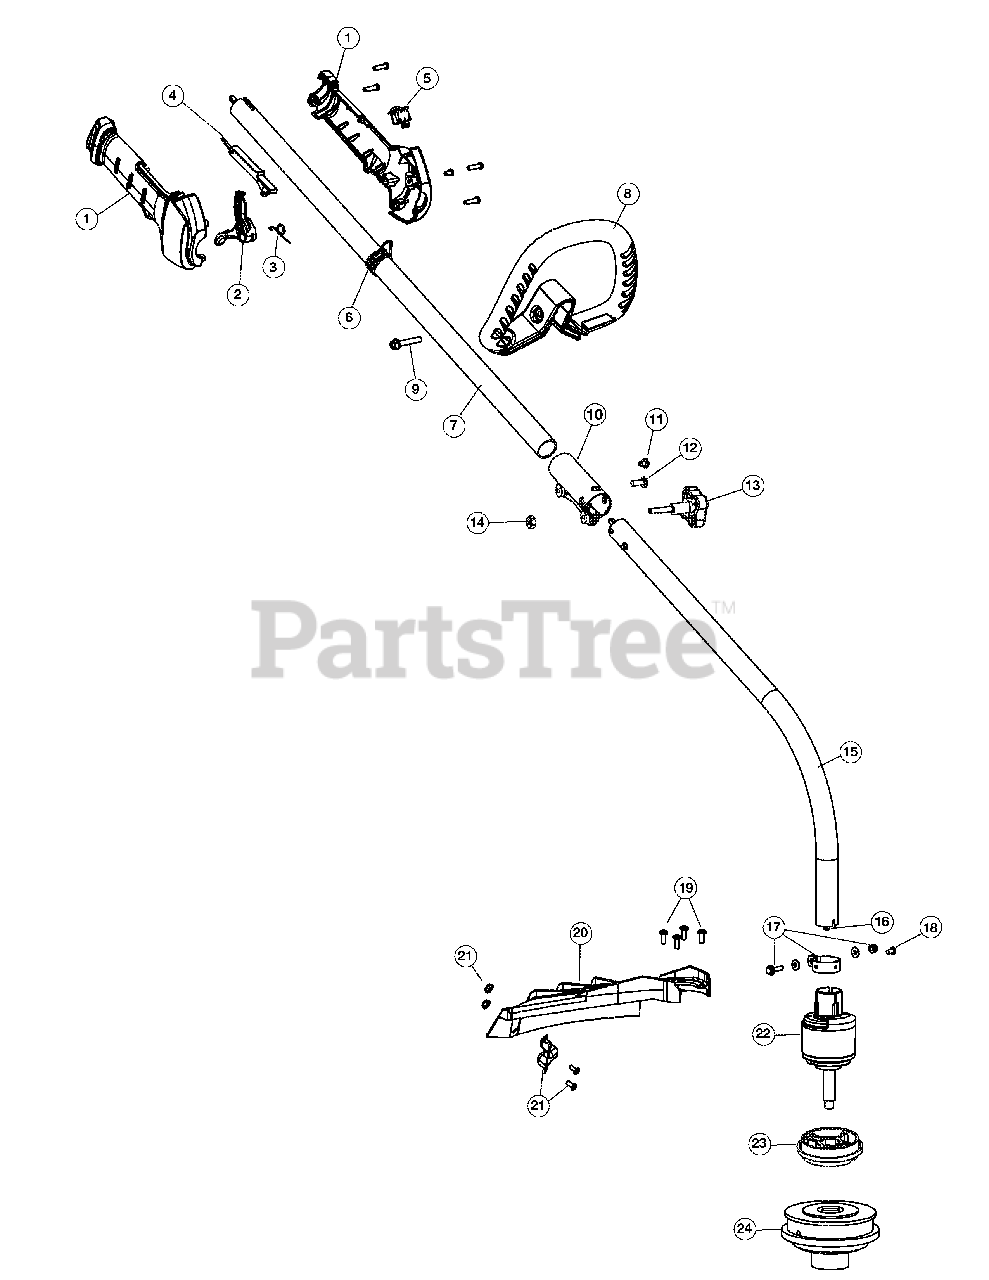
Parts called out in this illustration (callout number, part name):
1	Throttle Housing Assembly (Incl. Ref No. 2-5)
2	Throttle Trigger
4	Throttle Lock-Out
6	Shoulder Strap Clip
7	Upper Driver Shaft Housing Assembly
8	D-Handle Assembly (Incl. Ref No. 9)
10	Split Boom Coupler (Incl. Ref No. 11-14)
11	Anti-Rotation Screw
13	Adjustment Knob
14	Knob Retaining Nut
15	Lower Drive Shaft Assembly (Incl. Ref No. 16)
16	Flexible Drive Shaft
17	Lower Clamp Assembly (Incl. Ref No. 18)
18	Anti-Rotation Screw
19	Shield Mounting Screw
20	Shield Assembly (Incl. Ref No. 21)
21	Blade Assembly
23	Gearbox Spacer
24	Cutting Head Assembly
